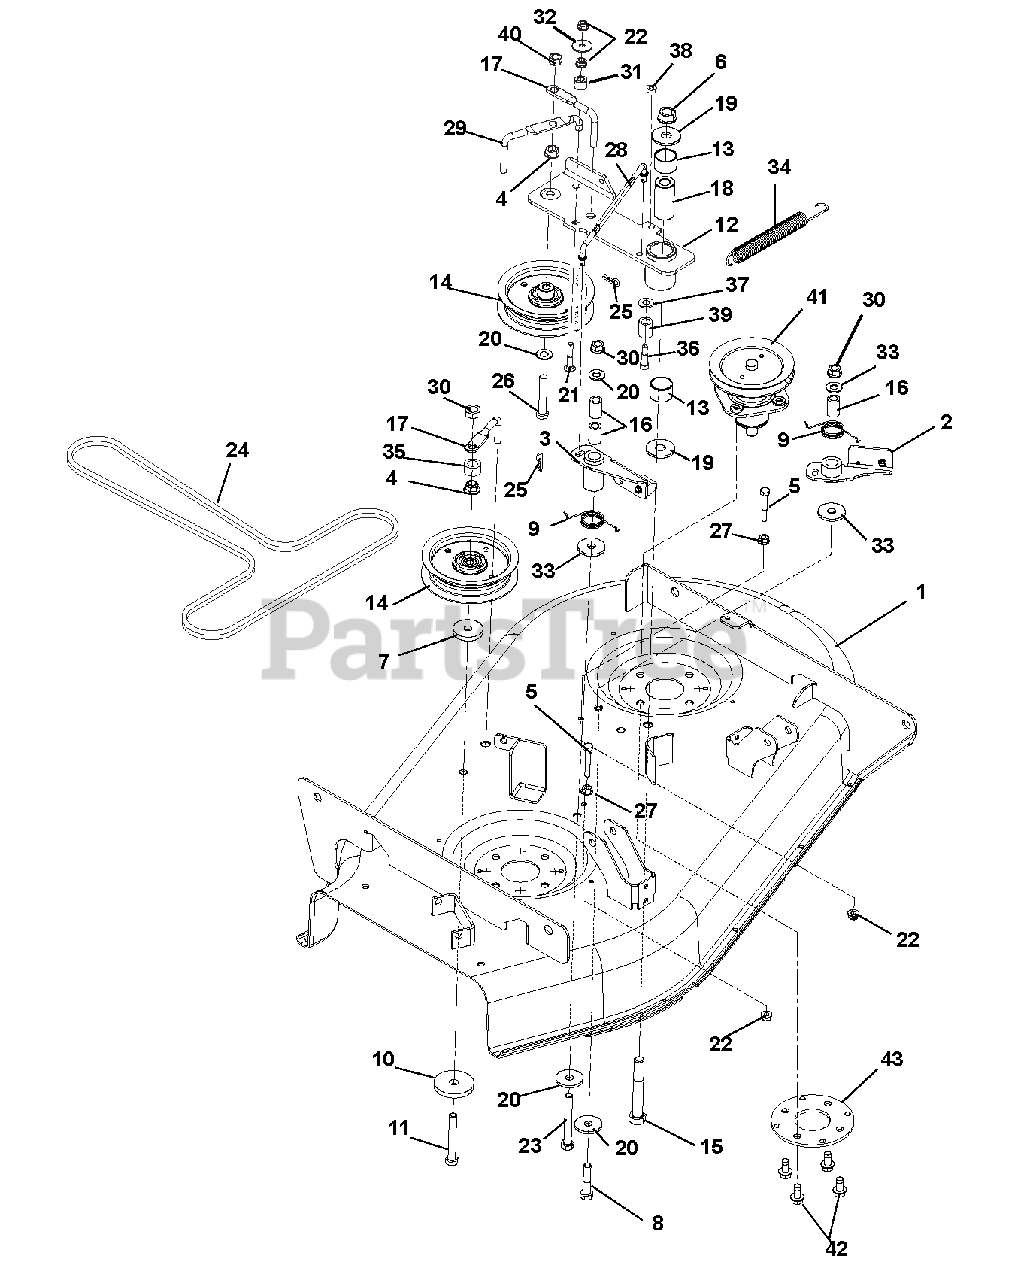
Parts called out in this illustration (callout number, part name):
1	WMT, BBZ 34 DECK
2	ASSY-BRAKE ARM LH
3	ASSY-BRAKE ARM RH
4	@NUT-LK-TOP-FLG .38-16 YWZC
5	@BLT-HEX .25-20X1.75 GR5 YWZC
6	@NUT-LK-TOP-FLG .50-13 YWZC
7	WSHR,FLT STL.406X1.50X.245YWZC
8	@BLT-HEX .38-16X1.75 GR5 YWZC
9	SPRING, TORSION
10	WSHR-FL-STL .469X2.00X.25 YWZC
11	@BLT-HEX .38-16X2.75 GR5 YWZC
12	WMT, IDLER ARM
13	BRG, 1.00 X 1.12 X .75
14	ASM, IDLER 4"
15	@BLT-HEX .50-13X3.50 GR5 YWZC
16	BUSH.,S.391X.622X.950 ST
17	WIREFORM, BELT FINGER
18	BSHG, SPCR .502X.997X2.03 PM
19	WSHR-FL-STL.511X1.441X.125 YWZ
20	@WSHR-FL-STL.406X.812X.065 YWZ
21	@BLT-RDHDSQNK .25-20X1.50 G5YZ
22	@NUT-LK-NYL-FLG .25-20 YWZC
23	@BLT-HEX .38-16X2.75 GR5 YWZC
24	V-BELT, HA-WRAPPED
25	PIN-HAIR INT .08X.18X1.18 YWZC
26	@BLT-HEX .38-16X2.25 GR5 YWZC
27	@NUT-SPNLK-FLG .25-20 YWZC
28	WIREFORM-LINK, BRAKE
29	WIREFORM, BELT FINGER
30	@NUT-LK-CTR-JAM .375-16 YWZC
31	SPACER .325 X.625 X.455
32	WSHR-FL-STL .281X1.000X.063
33	WSHR-FL-STL .406X1.375X.135 YZ
34	SG-TENS .062X.56X8.0 WLD 11
35	BSHG-SLV .377X.624X.370
36	BLT-SHSB .25-20X.312X.625
37	@WSHR-FL-STL.250X.56X.049 YWZC
38	NUT-LK-CTR JAM .25-20 YWZC
39	ROLLER-.50X.328X.625
40	@NUT-LK-CTR .38-16 YWZC
41	KIT, DECK SPINDLE ASM (34/50)
42	@SCR-TAP .38-16X.75 HWH TR YWZ
43	PLATE-REINF, SPINDLE
